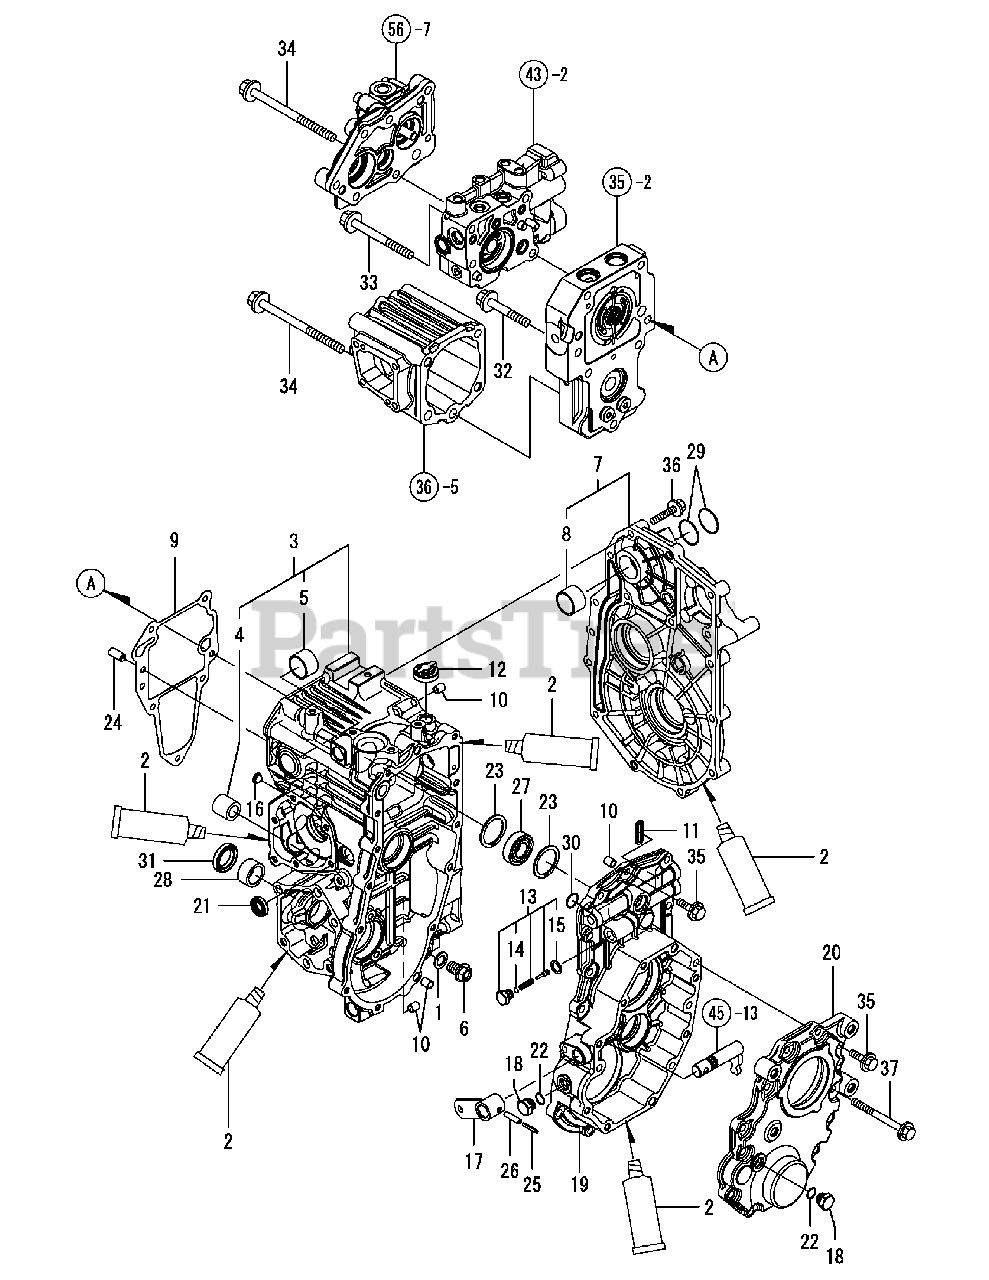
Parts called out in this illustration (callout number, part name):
2	SEALANT
3	HOUSING KIT, MISSION
6	DRAIN BOLT M14X20
7	COVER KIT, MISSION
9	PACKING, CENTER CASE
10	COLLAR 8 x 10 x 11.5
13	RELIEF KIT, PTO
15	GASKET 12, ROUND
18	PLUG 9/16-18UNF
19	CASE, REAR PTO
20	COVER, REAR PTO CASE
21	SEAL TC16 26 6, OIL
24	PARALLEL PIN, M10X20
25	SPRING PIN 3.5X25
26	SPRING PIN 6X25
27	BALL BEARING #6004
28	NEEDLE BEARING
29	O-RING 1A P-26.0
30	O-RING, 1A 19017
31	SEAL TC25 38 07, OIL
33	BOLT W/WASHER 10x105
34	BOLT, 10 X 145
35	BOLT M 8X 30 PLATED
36	BOLT M 8X 40 PLATED
37	BOLT M 8X 90 PLATED
